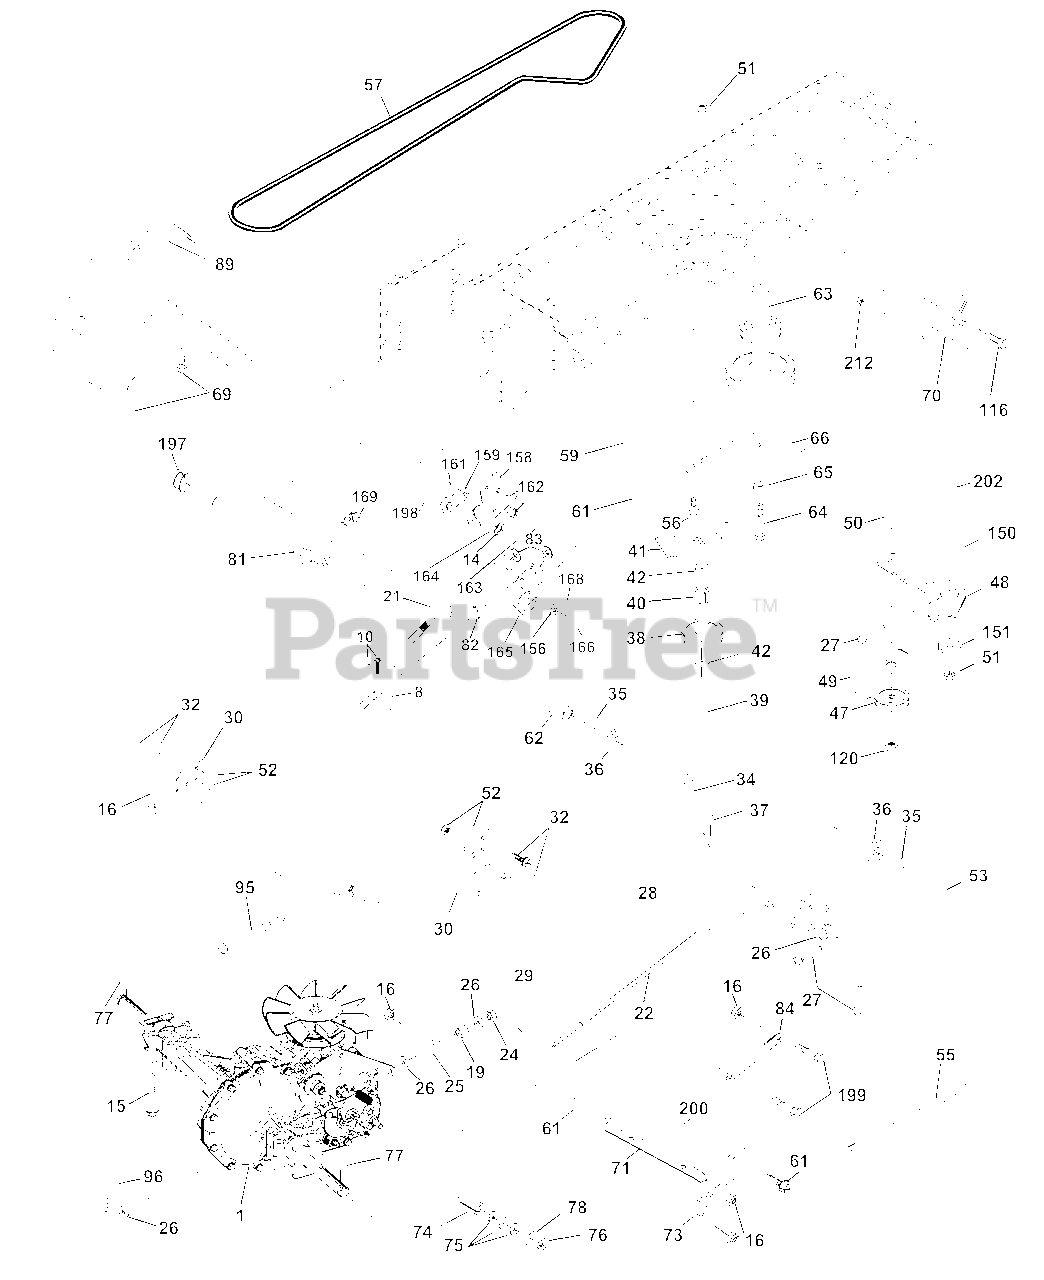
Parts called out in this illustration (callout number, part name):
8	Rod Shift Fender
10	Pin Cotter 1/8 x 1 CAD
14	Washer Lock Hvy Helical 1/4
15	Bolt Hex Flg Hd 5/16-18 X Gr.5
16	Nut Lock Hex W/Ins. 5/16-18 Unc P
19	Nut Lock Hex W/Wsh 3/8-16 Unc
21	Knob, Deluxe
22	Rod, Brake Hydro
24	Nut
25	Spring, Brake Rod
26	Washer
27	Pin Cotter 1/8 x 3/4 CAD.
28	Rod, Parking Brake
29	Cap, Parking Brake
30	Bracket, Transaxle
32	Bolt Hex Hd 5/16-18 Unc x 3/4
34	Shaft, Foot Pedal
35	Bearing, Nylon
37	Pin, Roll
38	Pulley, Composite, Flat
39	Bolt
40	Spacer, Split
41	Keeper, Belt Idler
42	Washer 13/32 x 13/16 x 12 Gauge
47	Pulley, Idler, V-Groove
48	Bellcrank Clutch Grnd Drv Stl
49	Retainer, Belt
50	Bolt
52	Nut Crownlock 5/16-18
53	Link, Clutch
55	Spring, Return, Clutch
56	Screw 3/8-16 x 1.0
57	V-Belt, Ground Drive
59	Keeper, Center Span
61	Screw 3/8-16 x 3/4
62	Cover, Pedal
63	Pulley, Clutch Eng
64	Bolt Hex 7/16-20 x 4 Ga. 5
65	Washer
66	Keeper Belt Engine
69	Screw Hex Wsh Hi-Lo 1/4-1/2 Unc
70	Guide Belt Mower Drive RH
71	Strap Torque Lh Hydro
73	Strap Torque Rh Hydro
74	Spacer, Axle
75	Washer 25/32 x 1-1/4 x 16 Gauge
77	Key, Square
78	Washer 25/32 x 1-5/8 x 16 Gauge
81	Shaft Asm. Cross Hydro
82	Spring Torsion T/A
83	Washer 17/32 x 3/4 x 16 Ga.
84	Link Transaxle
89	Console, Shift
95	Control Asm Bypass Hydro
96	Retainer Spring 1" Zinc/Cad
103	Nut Hex Jam Toplock 1/2-20 Unf
116	Boulon 3/8-16 x 1
120	Nut Lock Flg 3/8-16
150	Spacer Retainer
151	Washer 13/32 x 2 x 10 Ga.
156	Washer Srrtd 5/16 ID x 1.0 x .125 Tk
158	Bracket Shift Mount
159	Hub Tapered Flange Shift LT
161	Bolt Rdhd Sqnk 1/4-20 x 3/4 Gr. 5
162	Nut Crownlock 1/4-20 Unc
163	Bolt Hex Fin 1/4-20 unc x 1 Gr. 5
164	Washer 5/8 x .281 x 10 Ga
165	Bracket Pivot Lever
166	Screw 5/16-18 x 5/8 TT Yellow
168	Bolt Shoulder 5/16-18 x .561 TT
169	Plate Fastening Cross Shf. STLT/CRD
197	Nyliner Snap-In 5/8" ID
198	Washer Nyl. 7/8 ID x .105"
199	Bolt Shoulder 5/16-18 Unc
200	Bolt Rdhd Sq Neck 5/16-18unc x 1
202	Bolt Carr Sh 3/8-16 x 1-3/4 Gr. 5
205	Washer 17/32 x 1 x 16 Ga.
212	Nut Hex Flg Lock
